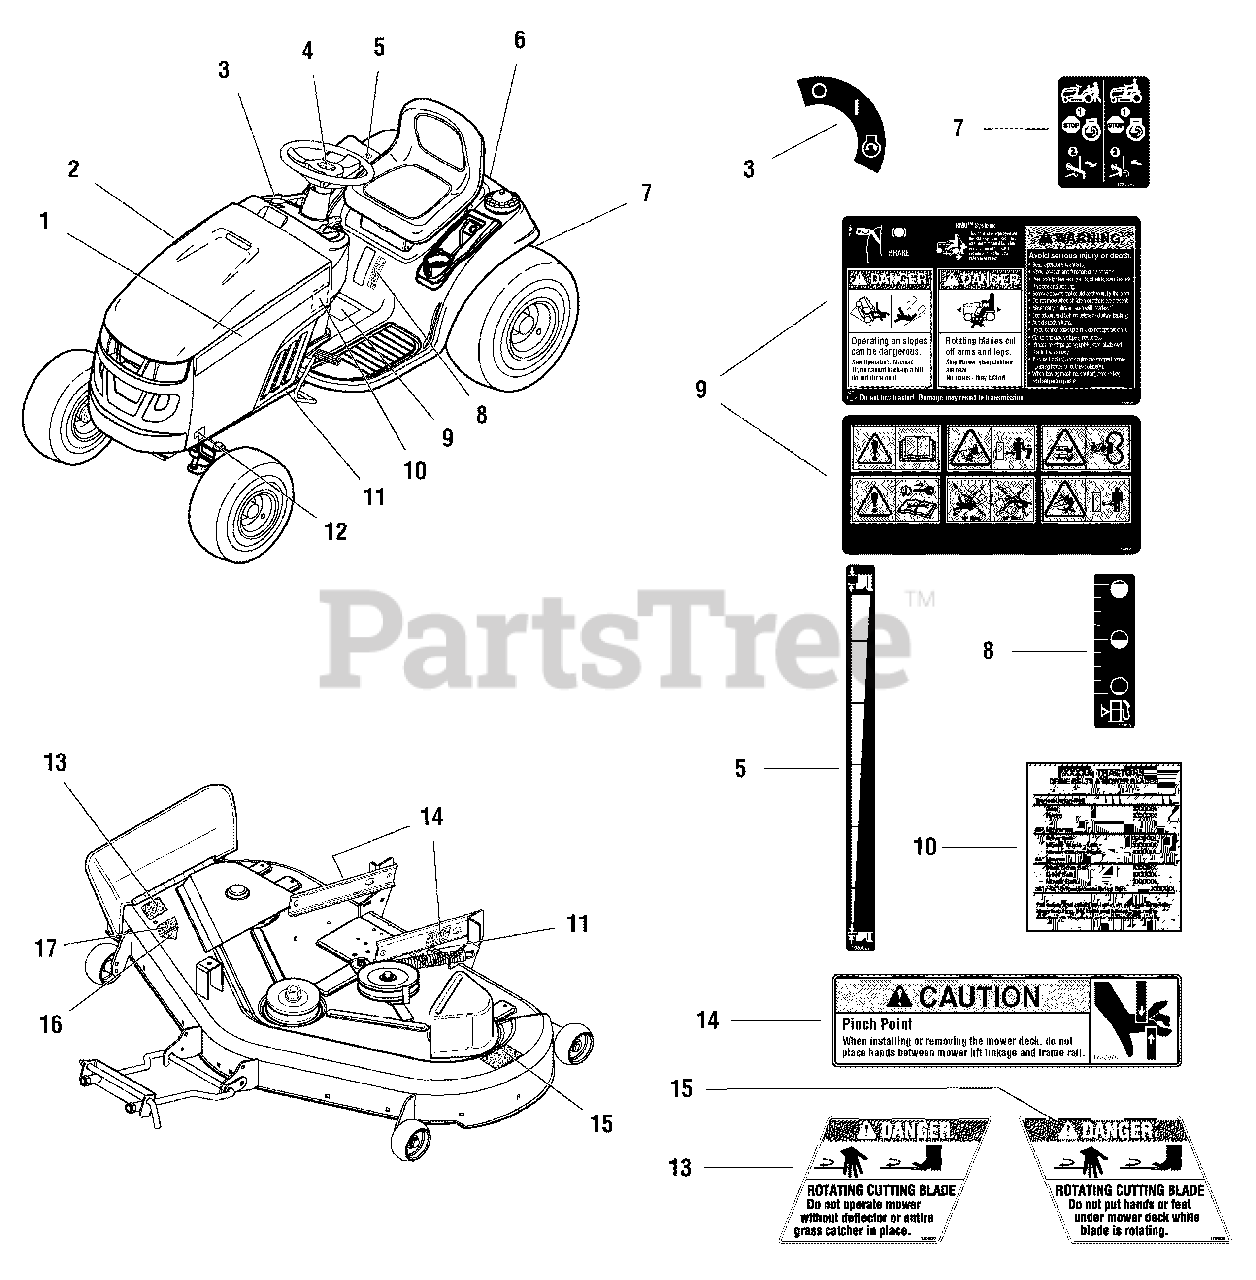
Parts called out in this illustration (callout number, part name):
1	DECAL, Snapper, LH Hood Stripe
2	DECAL, Snapper, RH Hood Stripe
3	DECAL, Ignition Switch Symbol, White/Black
4	DECAL, Steering Wheel Icon
5	DECAL, Height of Cut
6	DECAL, Snapper Rear Stripe, Silver/ 8.5LG
7	DECAL, Transmission Tow/ Release Lever
8	DECAL, Fuel Level
9	DECAL, Danger Slopes
10	DECAL, Belts, Blades
11	DECAL, ID Plate
12	DECAL, LT200 18.5HP
13	DECAL, Danger, Chute in Place
14	DECAL, CAUTION! Pinch Point
15	DECAL, Danger, Hand Under Deck
16	DECAL, OPEI
17	DECAL, 44"
